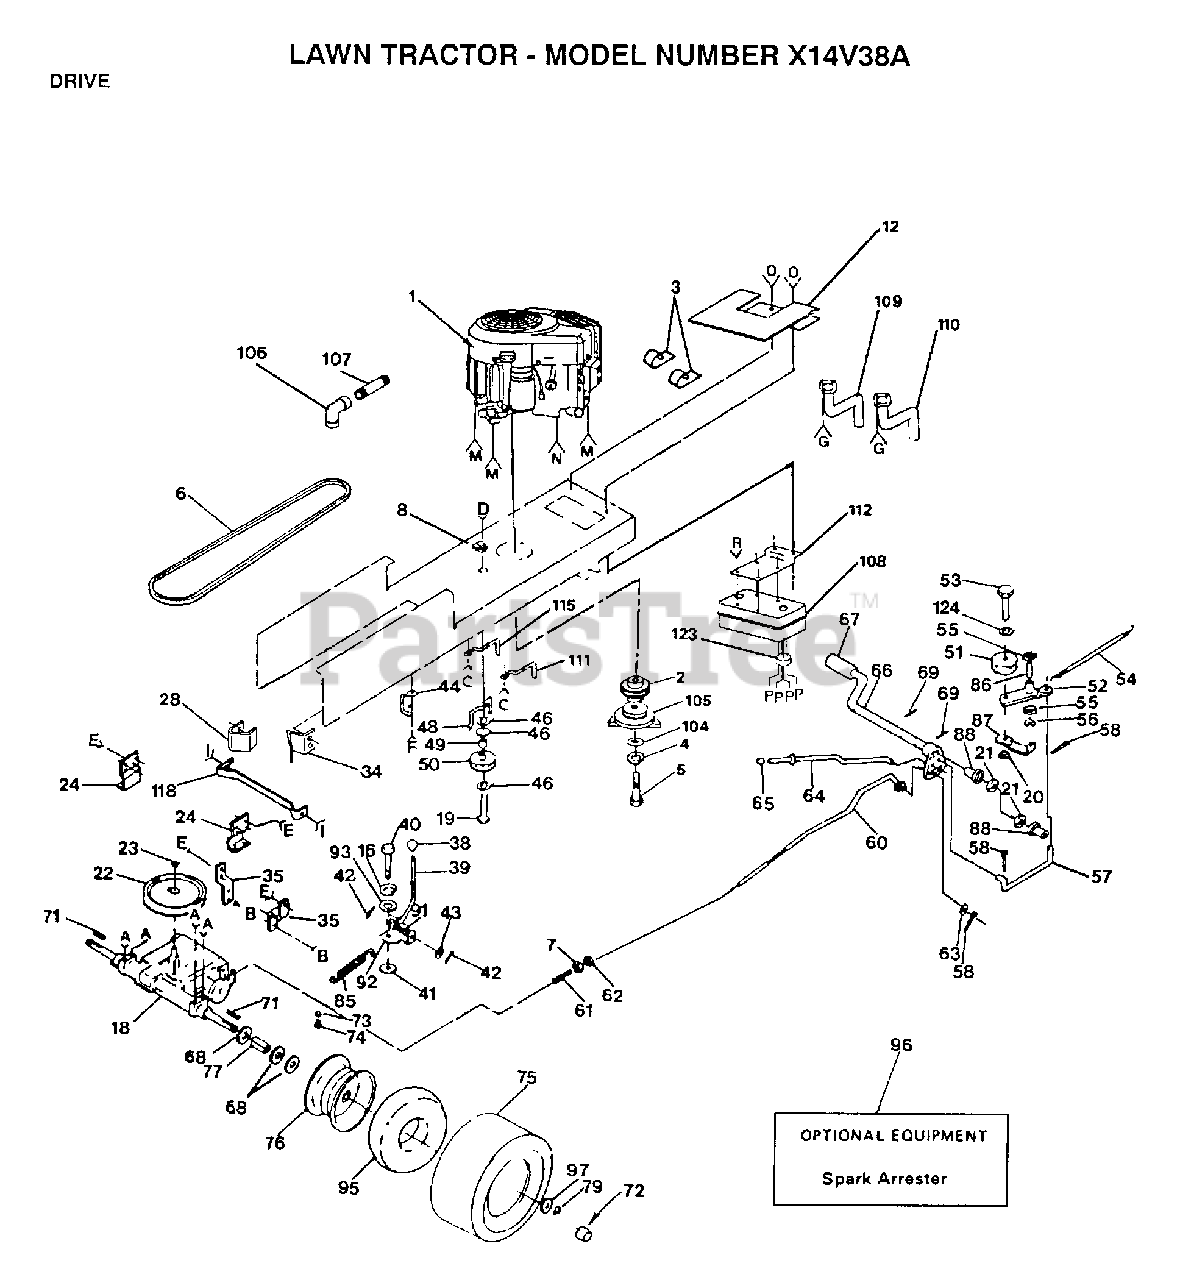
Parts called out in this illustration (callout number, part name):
1	PIPE, EXHAUST
4	LOCKWASHER
5	BOLT
6	BELT-V.90.0.GD.DR
7	NUT
8	CLIP T
16	LOCKWASHER
19	BOLT
21	WASHER LT
22	PULLEY TRANS
24	BRACKET LT
28	"KEEPER,BELT LH T"
34	"KEEPER,BELT RH T"
35	STRAP TORQUE
38	CONTROL KNOB LT
39	ROD SHIFTER
41	WASH-SHFT PLT LT
42	PIN COTTER 1/8
43	WASHER
46	WASHER
48	BELT KEEPER LT
49	SPACER T
50	PULLEY.IDLER.FLAT
52	ARM IDLER
54	"SPRING, RETURN LT"
55	WASHER LT
56	KLIP RING
57	"LINK, CLUTCH T"
58	COTTER PIN
60	BRAKE ROD LT
61	SPRING ROD LT
62	NUT
63	WASHER
65	PLUNGER CAP T
67	PEDAL COVER T
68	WASHER
71	SQUARE KEY
72	HUB CAP
73	VALVE CAP
74	VALVE STEM LT
75	TIRE.TS2.18X8.5
77	SPACER LT
79	E-RING LT
86	"LY, BEARING"
87	RETAIN BELT
88	NYLON BEARING
91	SPRING LT
92	PLATE SHIFT LT
93	WASHER LT
95	TUBE.18X9.5-8
96	SPARK ARREST KIT
97	WASHER
104	WASHER
106	ELBOW
107	PIPE NIPPLE LT
109	TUBE ASSY EXH LH
110	TUBE ASSY EXH RH
111	"KEEPER,BLT ENG LT"
112	BRACKET MUFFLER
115	KEEPER BELT ENGLH
123	DEFLECTOR.222573
